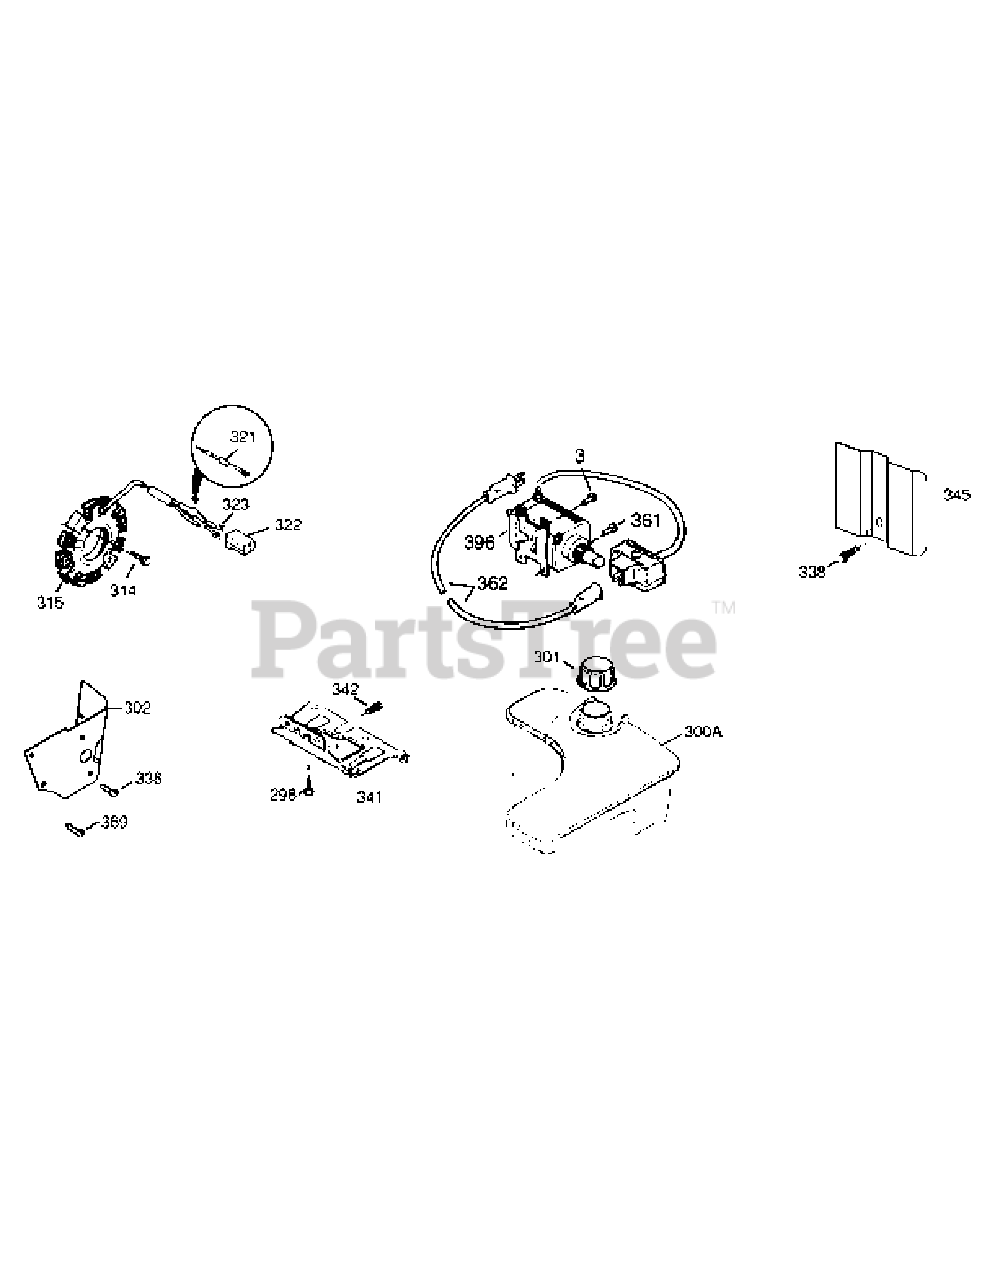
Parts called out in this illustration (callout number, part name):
3	Screw, 1/4-20 x 1/2"
149A	Intake Valve Seal
157A	Jam Nut, 5/16-24
238	Screw, 10-32 x 1/2"
290	Fuel Line (32.0" Length)
298	Screw, 1/4-15 x 3/4"
301	Fuel Cap (Red Plastic) (1-1/2" I.D.)
302	Fuel Tank Extension
309	Screw, 10-32 x 5/16"
314	Screw, 1/4-20 x 3/4"
315	Alternator Coil (18 watt)
338	Screw, 10-32 x 1/2"
341	Fuel Tank Bracket
342A	Screw, 5/16-18 x 7/8"
345	Heat Baffle
361	Screw, T-30, 1/4- 20 x 15/32"
369	Screw, 12-16 x 5/8"
396	Electric Starter Motor (120 volt)
704	Screw, 1/4-20 x 5/8"
999	Winter Maintenance Kit
